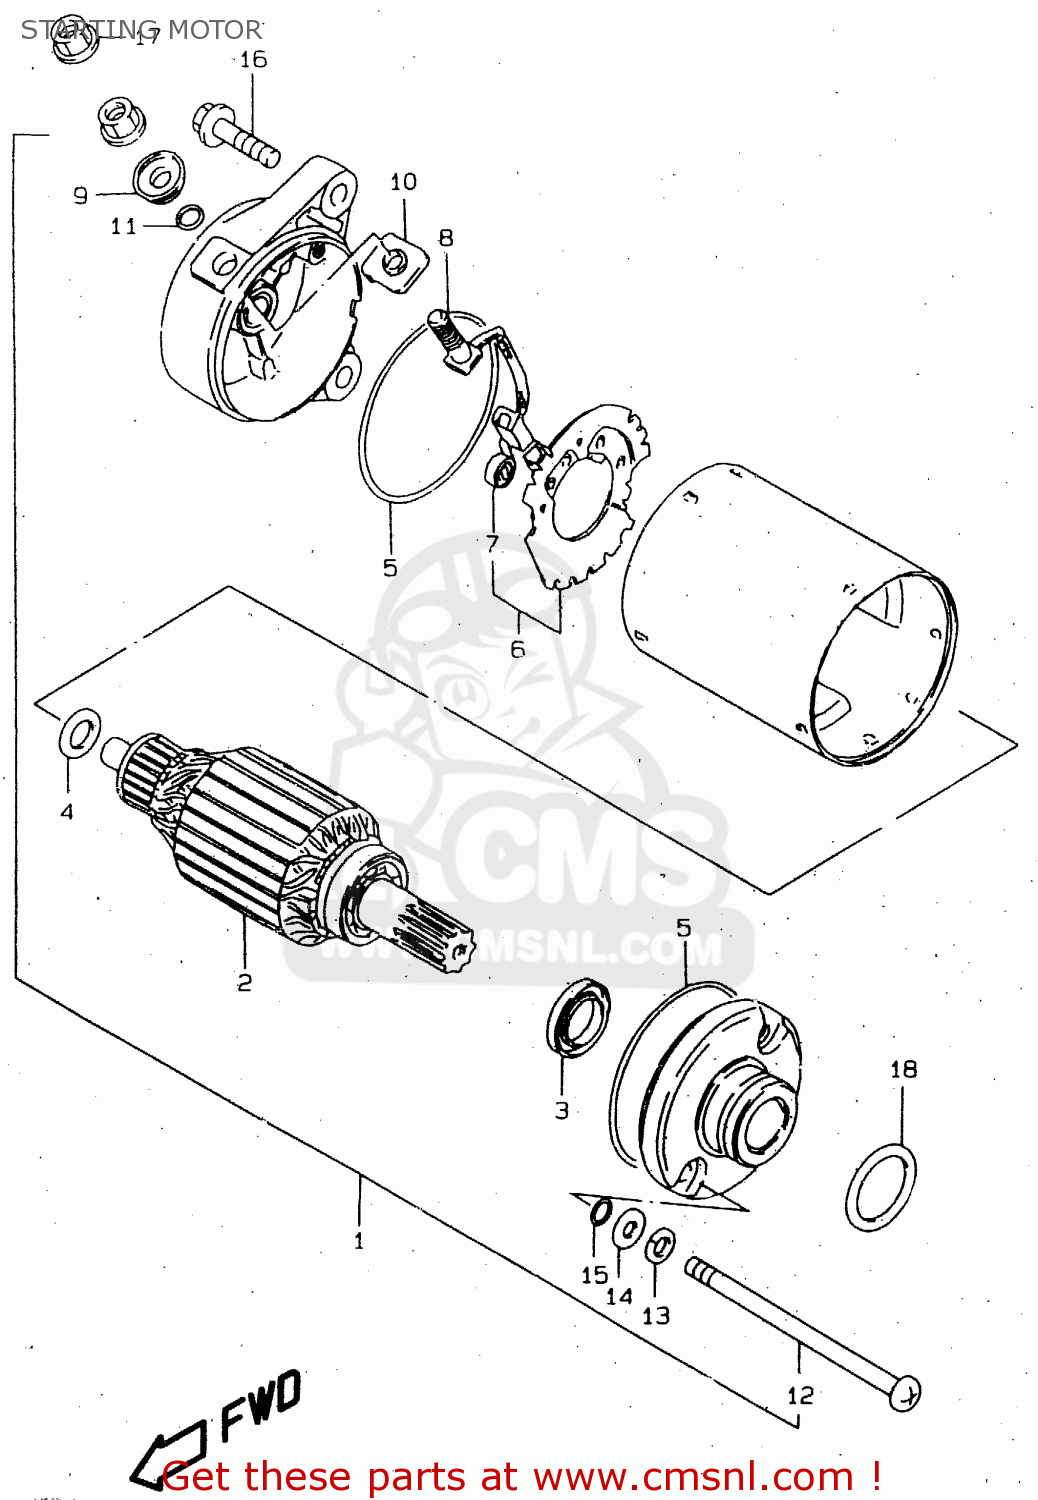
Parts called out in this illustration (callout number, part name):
1	MOTOR ASSY,STARTING
2	ARMATURE
3	SEAL,OIL
4	SHIM SET,STARTING MOTOR
5	O RING
6	HOLDER,BRUSH
7	SPRING
8	BRUSH SUB ASSY,STARTING MOTOR
9	BUSHING
10	BUSH,B
11	O RING
12	BOLT
13	WASHER,LOCK
14	WASHER
15	O RING
16	BOLT
17	NUT
18	O RING(D:3,ID:24.5)
